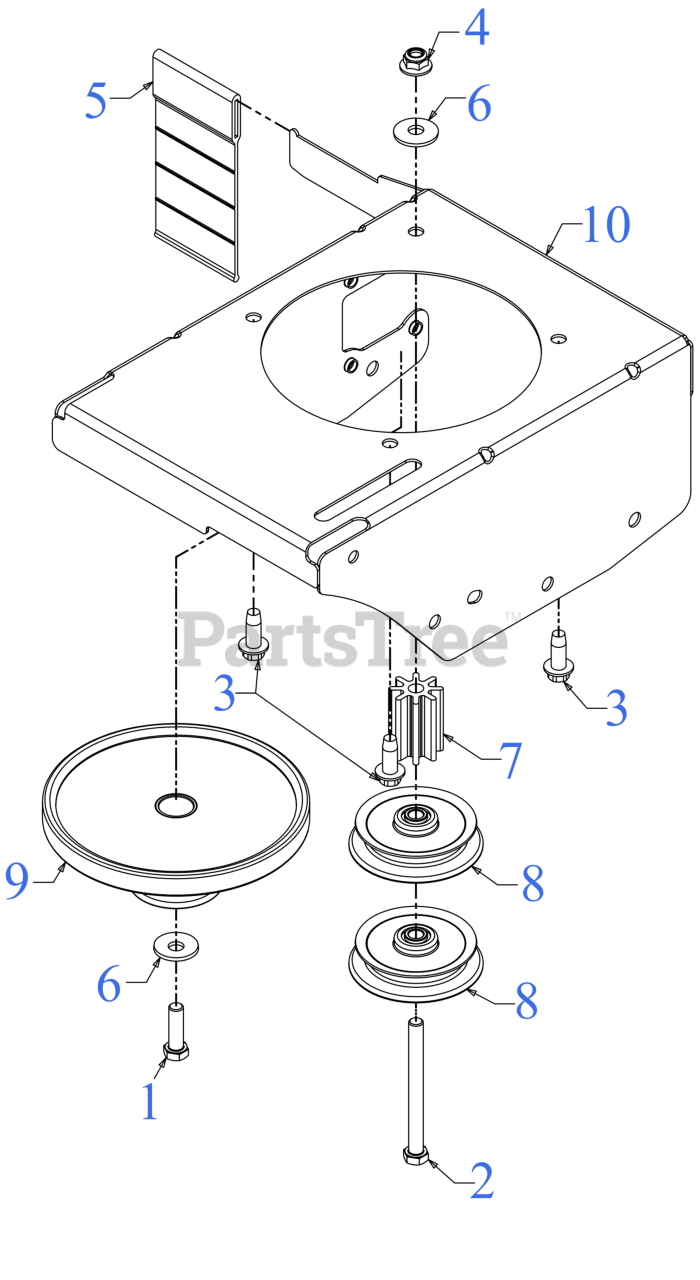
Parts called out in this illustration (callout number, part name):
1	SCREW 3/8-24X1.25
2	HEX SCREW 3/8-16 x 4.00
3	SCREW 3/8-16 x 1
5	EDGER BLADE GUARD
6	BELL WASHER
7	MOUNT SPACER
8	FLAT IDLER PULLEY
9	ENGINE PULLEY
